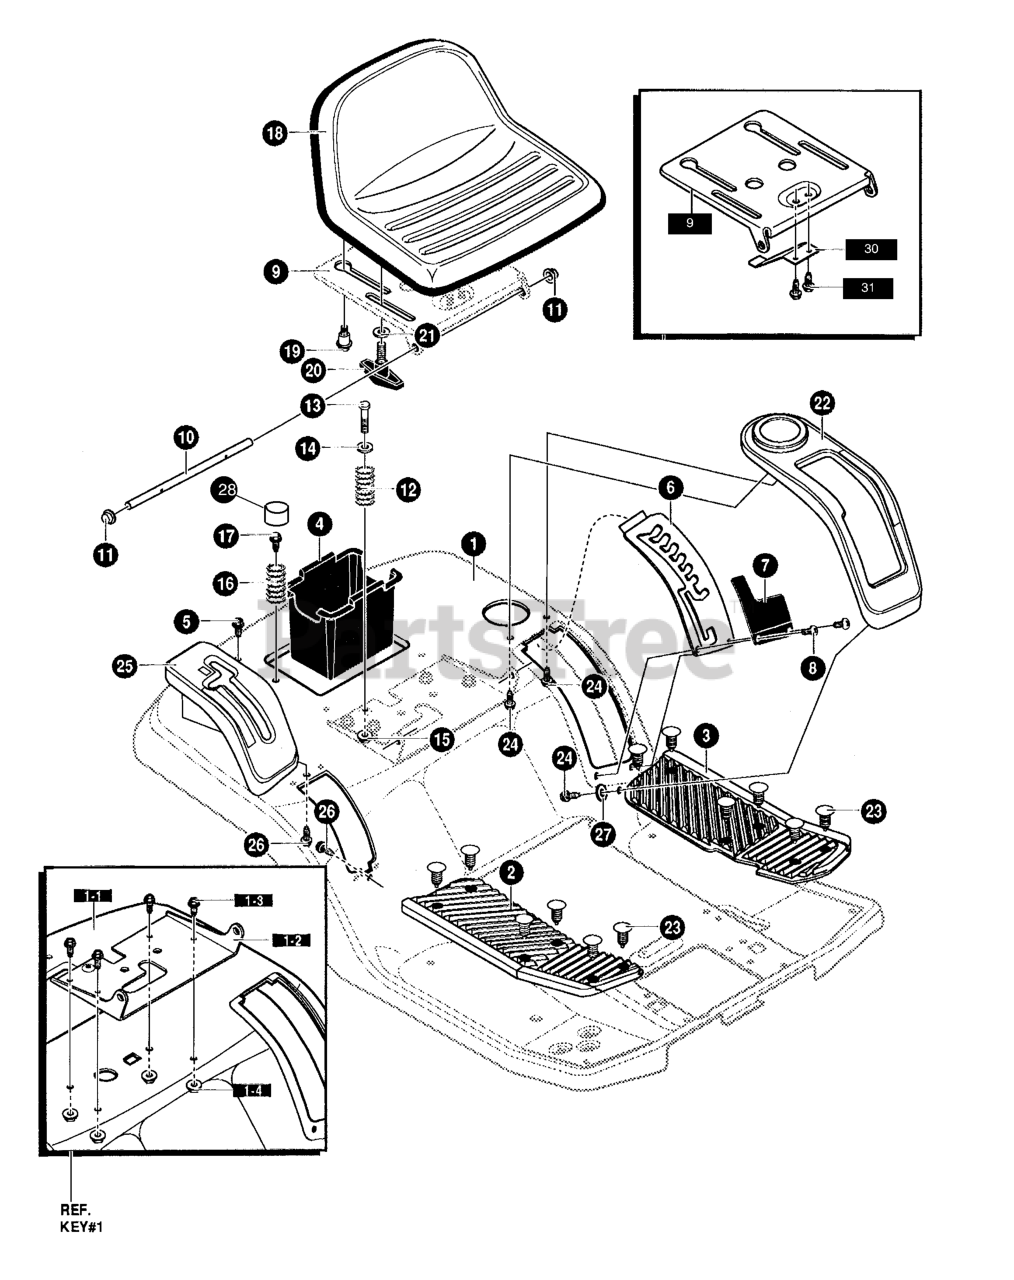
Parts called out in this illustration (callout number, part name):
1	LARGE SEAT DECK
1-1	SEAT DECK, LARGE
1-2	BRACKET, PIVOT SEAT
1-3	SCREW, 5/16-18 x 0.75
1-4	NUT, 5/16-18
2	FOOT REST PAD RH
3	FOOT REST PAD LH
4	CONTAINER, BATTERY
5	SCREW 1/4-20X.63
6	PLATE, LIFT DETENT
7	COVER, LIFT DETENT
9	SUPPORT, SEAT
10	HINGE SEAT PIVOT
11	NUT, PUSH CAP
12	SPRING, COMPRESS
13	BOLT, SHOULDER 1/4-20
14	WASHER CUP
15	NUT, 1/4-20
16	SPRING, COMPRESS
17	SCREW 5/16- 18X.75
18	SEAT
19	BOLT, SHOULDER 5/16- 18
20	BOLT, WING 5/16- 18X.50
21	Washer
22	COVER, DETENT PLATE
23	FASTENER, RATCHET
24	SCREW, 1/4- 15X.44/.53
25	COVER, SHIFT
26	SCREW, 1/4- 15X.44/.53
27	FLATWASHER
28	Cap
30	SPRING, LEAF
31	SCREW, 1/4-20X.50
